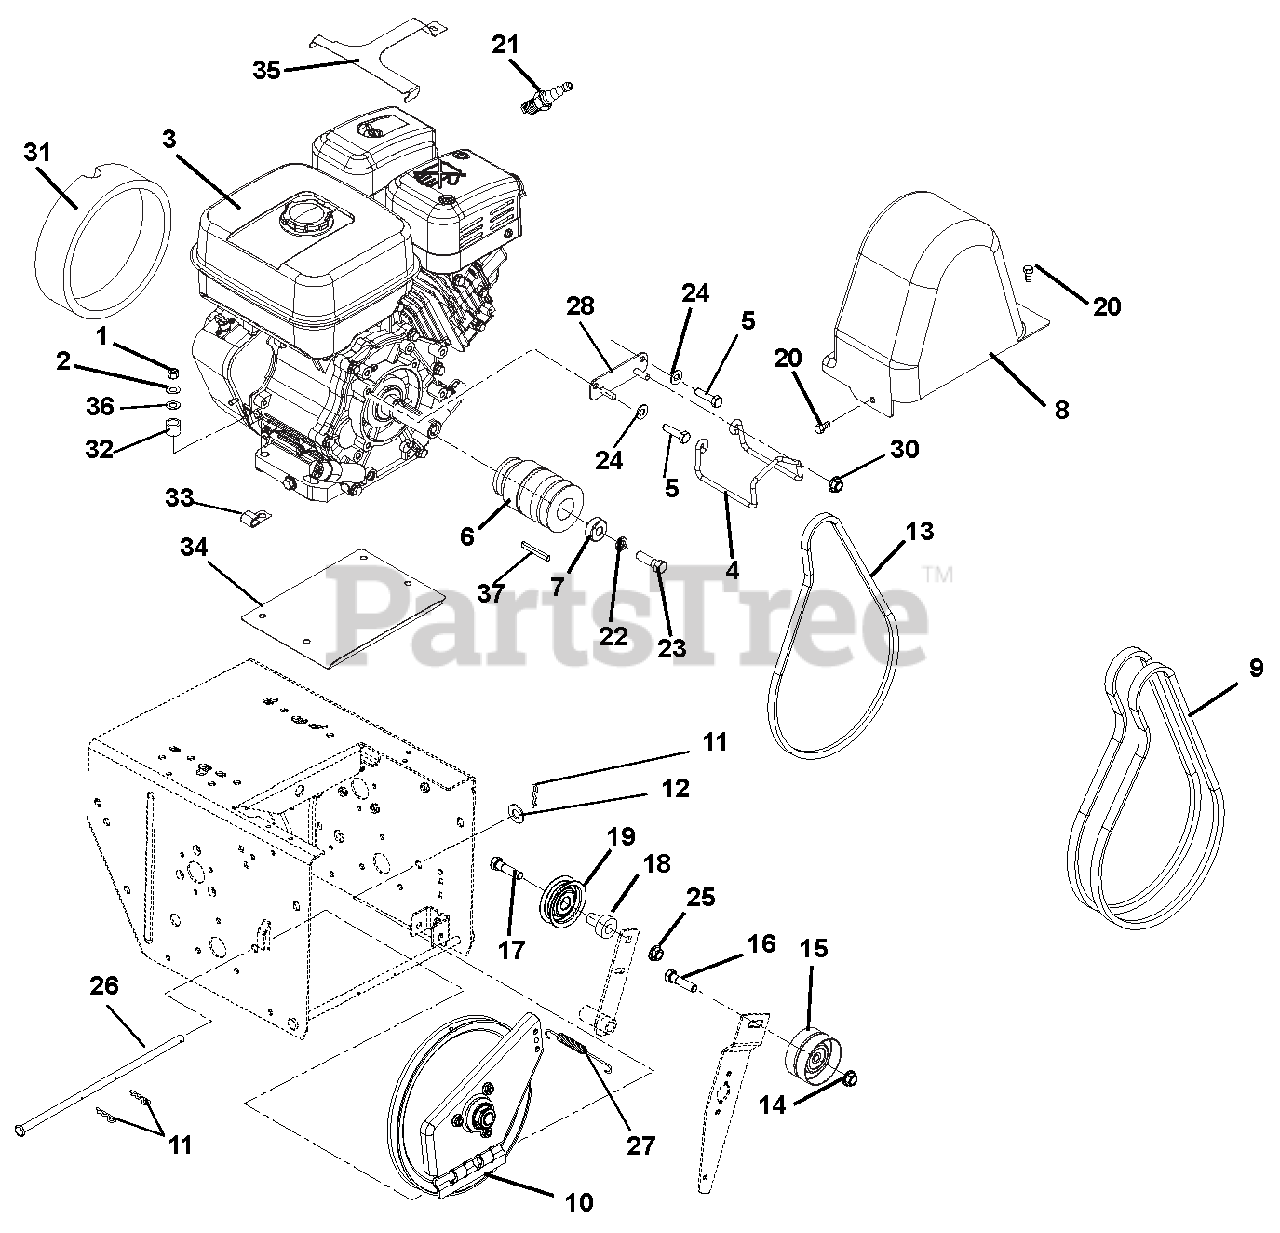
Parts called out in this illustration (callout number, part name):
1	@NUT-HEX .31-18 YWZC
2	WSHR-LK .312X.097 HVY YWZC
3	ENGINE,SUBARU EX27 AS RECOIL
4	FINGER, BELT
5	BLT-HEX .31-24X.75 YWZC GR5
6	SHEAVE, SUBARU EX27
7	BSHG-SPACER .47X1.25X.50
8	COVER, BELT-TALL PRO
9	V-BELT, HA-RAW EDGE (SET)
10	PLATE, SWING ASSEMBLY-DEEP
11	PIN-HAIR, ENDRIES #25 YWZC
12	@WSHR-FL-STL.406X.812X.065 YWZ
13	V-BELT, 3L-RAW EDGE
14	@NUT-LK-TOP-FLG .38-16 YWZC
15	IDLER, FLAT 2.75" DIA
16	@BLT-HEX .38-16X1.50 GR5 YWZC
17	@BLT-HEX .31-18X1.25 GR5 YWZC
18	SPCR, BRG .315X.50X.688X.281
19	IDLER
20	SCR-TAP .25-20X.50 HWH TR YWZ
21	PLUG, SPARK
22	@WSHR-LK .44X.109 REG YWZC
23	BLT-HEX .44-20X1.50 G5 YZ EP80
24	WSHR-LK .312X.097 HVY YWZC
25	@NUT-LK-TOP-FLG .31-18 YWZC
26	PIN, PIVOT
27	SG-TENS .048X.50X2.8
28	PLATE, BELT FINGER MOUNT
29	WSHR-FL-STL .536X1.07X.109 YZ
30	@NUT-LK-TOP-FLG .31-18 YWZC
31	FOAM COVER, RECOIL-SUBARU
32	BSHG-SLV .325X.400X.795
33	J-CLAMP
34	BAFFLE, WATER-PRO SERIES
35	GUARD, SNOW-SUBARU
36	@WSHR-FL-STL.38X.875X.083 YWZC
37	KEY .25X.25X2.25
